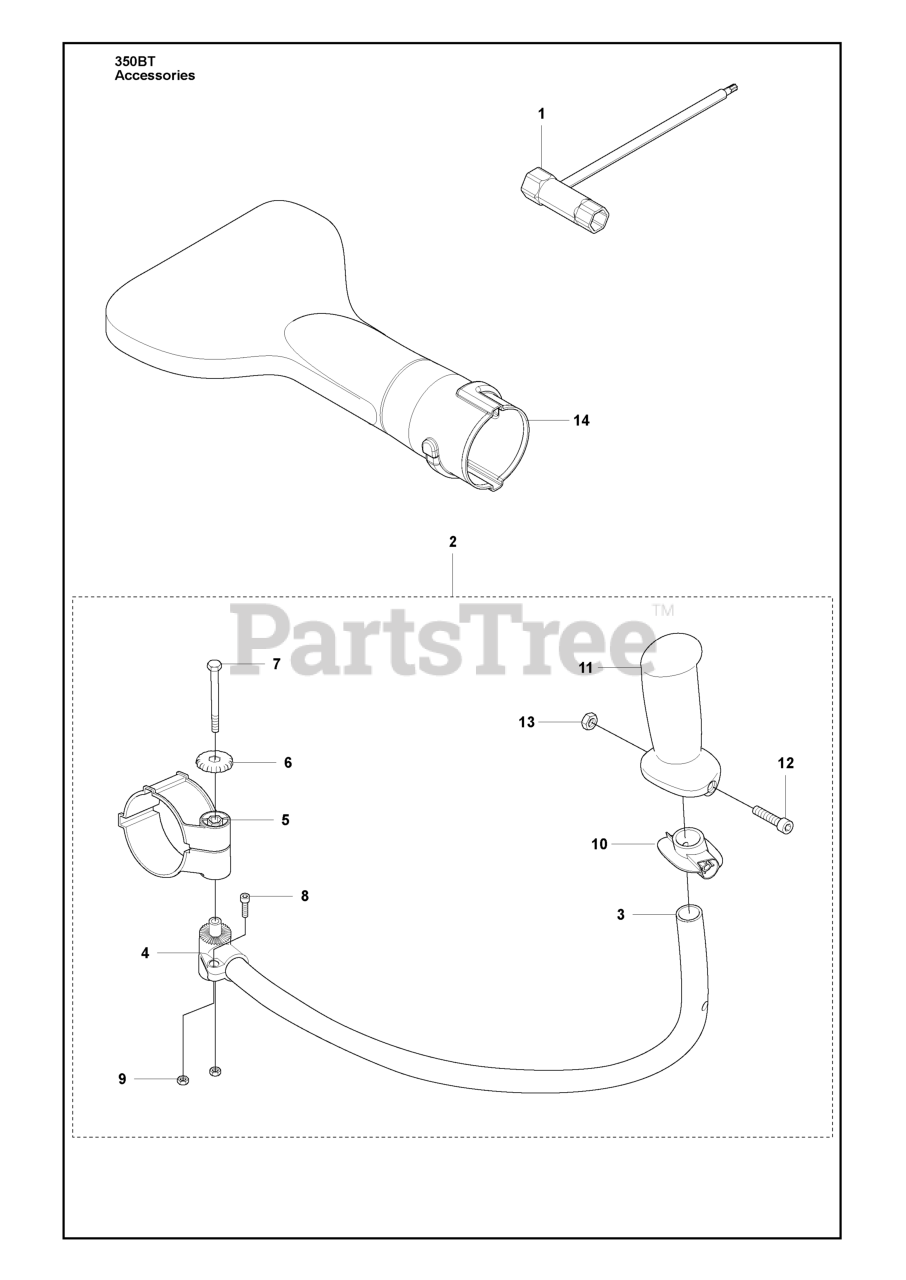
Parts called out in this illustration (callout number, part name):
1	SOCKET
2	HANDLEBAR ASSY
5	HOLDER TH
8	SCREW MC6S 5X10
14	FLAT NOZZLE
